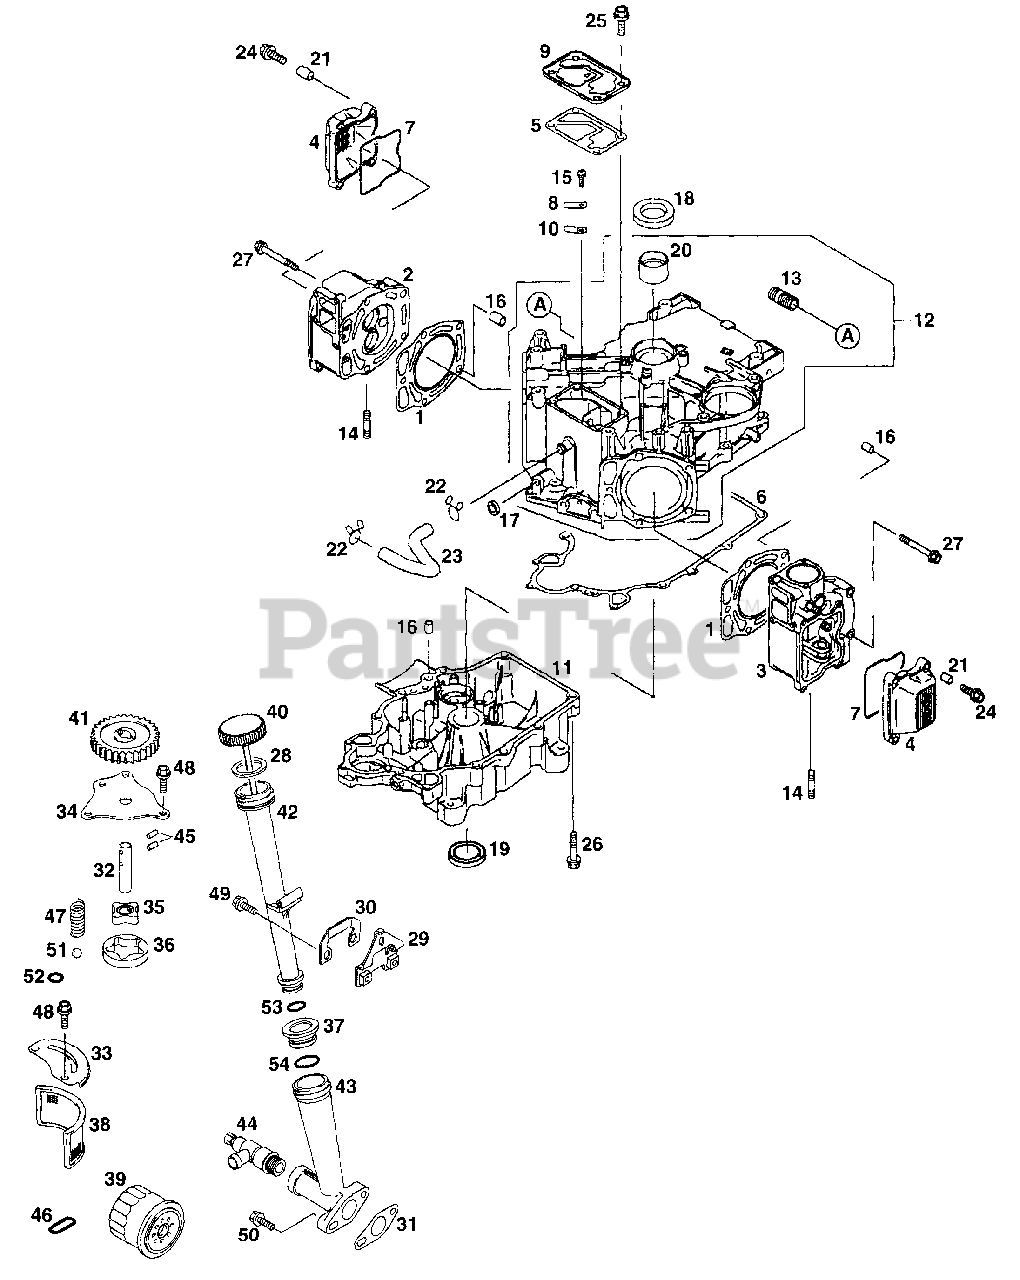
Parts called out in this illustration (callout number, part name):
2	Cylinder Head
3	Cylinder Head
6	Crankcase Cover Gasket
7	Rocker Case Gasket
11	Crankcase Cover
18	Oil Seal
20	Plane Bearing
24	Flanged Bolt
25	Flanged Bolt
26	Flanged Bolt
27	Flanged Bolt
28	Oil Gauge Gasket
31	Filler Gasket
32	Oil Pump Shaft
34	Oil Pump Cover
35	Pump Rotor, In
36	Pump Rotor, Out
39	Oil Filter
44	Fitting
47	Spring
48	Flanged Bolt
49	Flanged Bolt
50	Flanged Bolt
